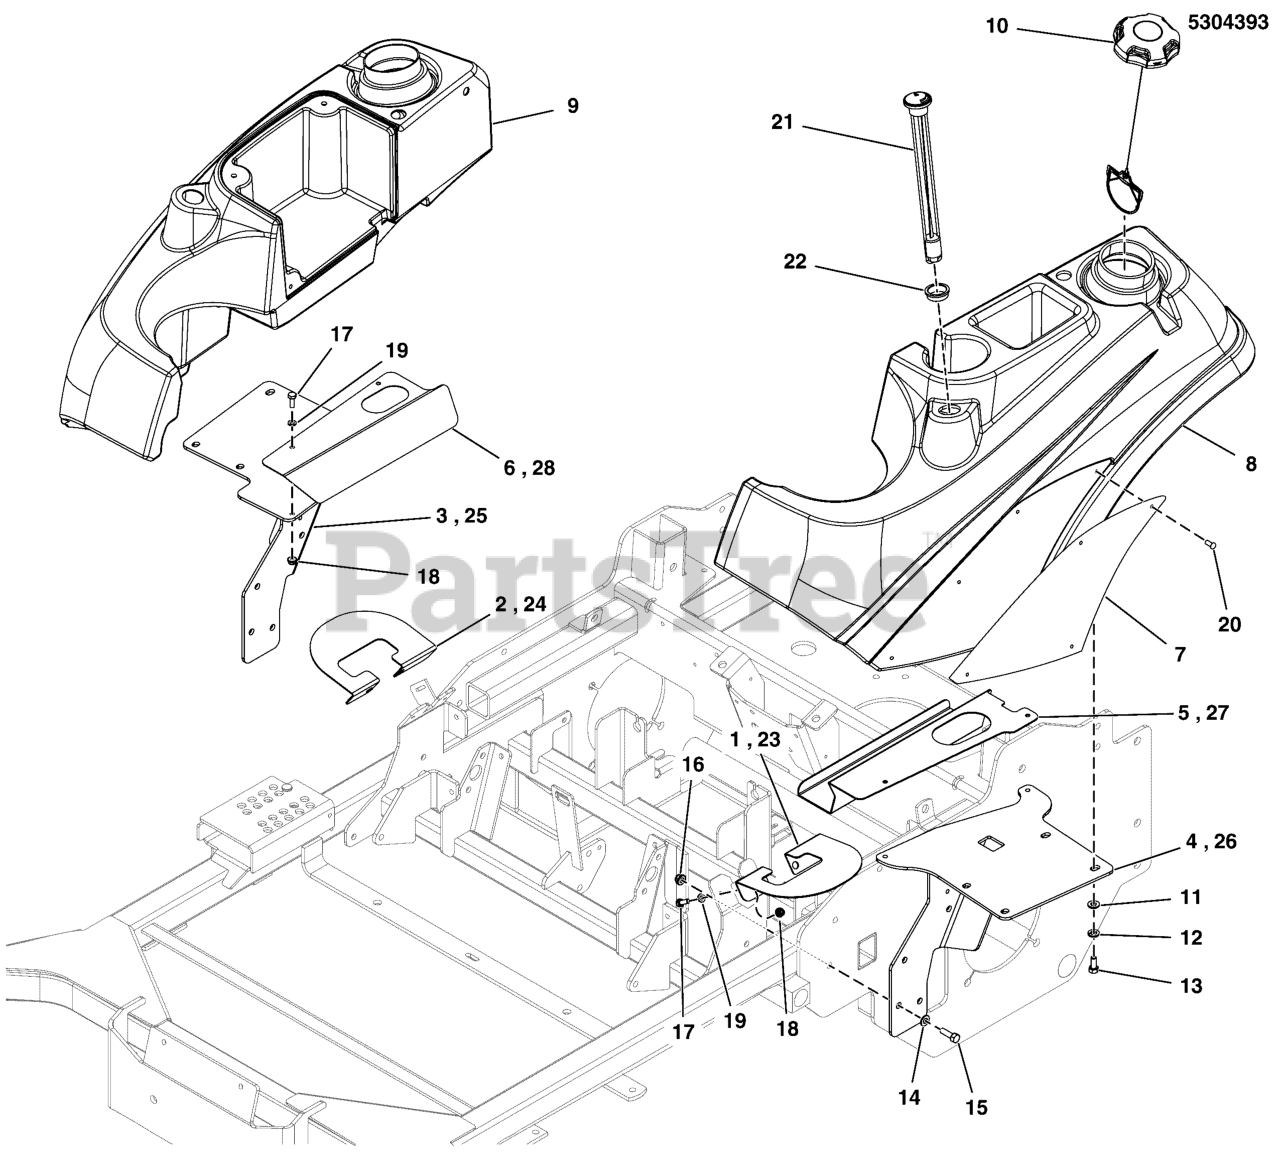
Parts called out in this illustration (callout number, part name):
1	PLATE,MOTION CONTROL GUARD F320/210Z LH, BLK
2	PLATE,MOTION CONTROL GUARD F320/210Z RH, BLK
3	WELD, FUEL MOUNT, RH, F210Z - BLK
4	WELD, FUEL MOUNT, LH, F210Z - BLK
5	GUARD, SEAT, LH, F210Z - BLK
6	GUARD, SEAT, RH, F210Z - BLK
7	BADGE, IS2000 - IS3000 - RED
8	TANK, FUEL, LH
9	TANK, FUEL, 5.25 GAL,MED, Z-RH, LOW PERM
10	FUEL CAP, 3-1/2", MANAGED VENT OUT, 12"
11	WASHER, 5/16 F436 FLAT
12	WASHER, 5/16 LOCK CZ
13	BOLT, 5/16-18 X 3/4 GD5
14	WASHER, 5/16" SAE
15	BOLT, 5/16-18 X 1 GD5 CZ
16	NUT, 5/16-18 HEX NYLOCK FLANGE
17	BOLT, 1/4-20 X 3/4 GD5 CZ
18	NUT, 1/4-20 HEX NYLOCK FLANGE
19	WASHER, 1/4 SAE
20	SCREW, #10-24 X 3/8 ALLEN BHBZ
21	GAUGE, FUEL, 12
22	GROMMET, FUEL GAUGE
23	PLATE,MOTION CONTROL GUARD F210Z LH, BLK
24	PLATE,MOTION CONTROL GUARD F210Z RH, BLK
25	WELD, FUEL MOUNT, RH, F210Z - BLK
26	WELD, FUEL MOUNT, LH, F210Z - BLK
27	GUARD, SEAT, LH - BLK
28	GUARD, SEAT, RH - BLK
